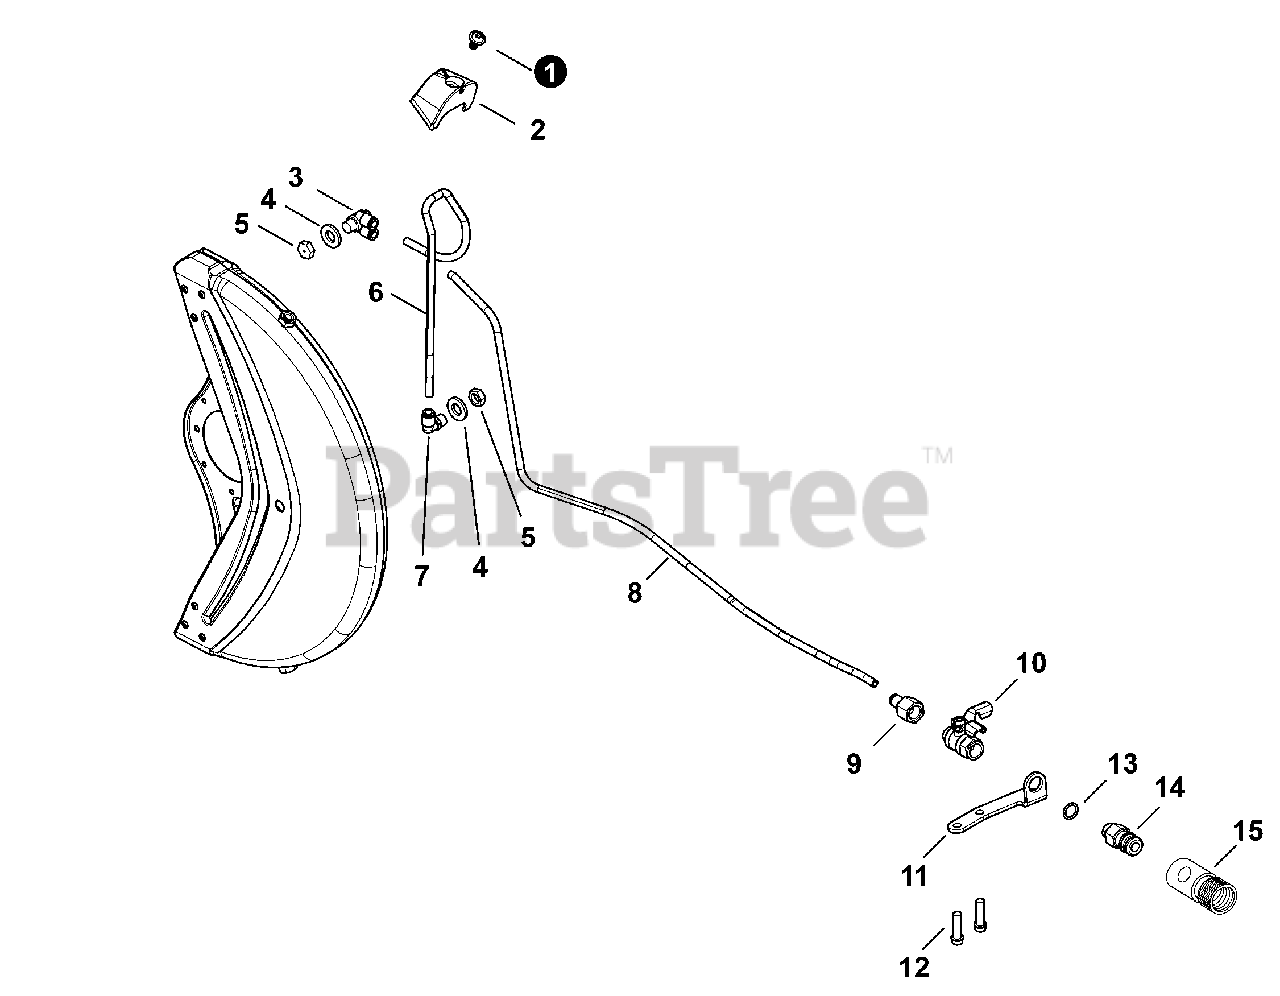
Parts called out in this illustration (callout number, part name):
3	CONNECTOR, PIPE
5	NUT, NOZZLE
7	CONNECTOR, PIPE
9	CONNECTOR, PIPE
10	PETCOCK
11	BRACKET
14	CONNECTOR, PIPE
15	COUPLER
